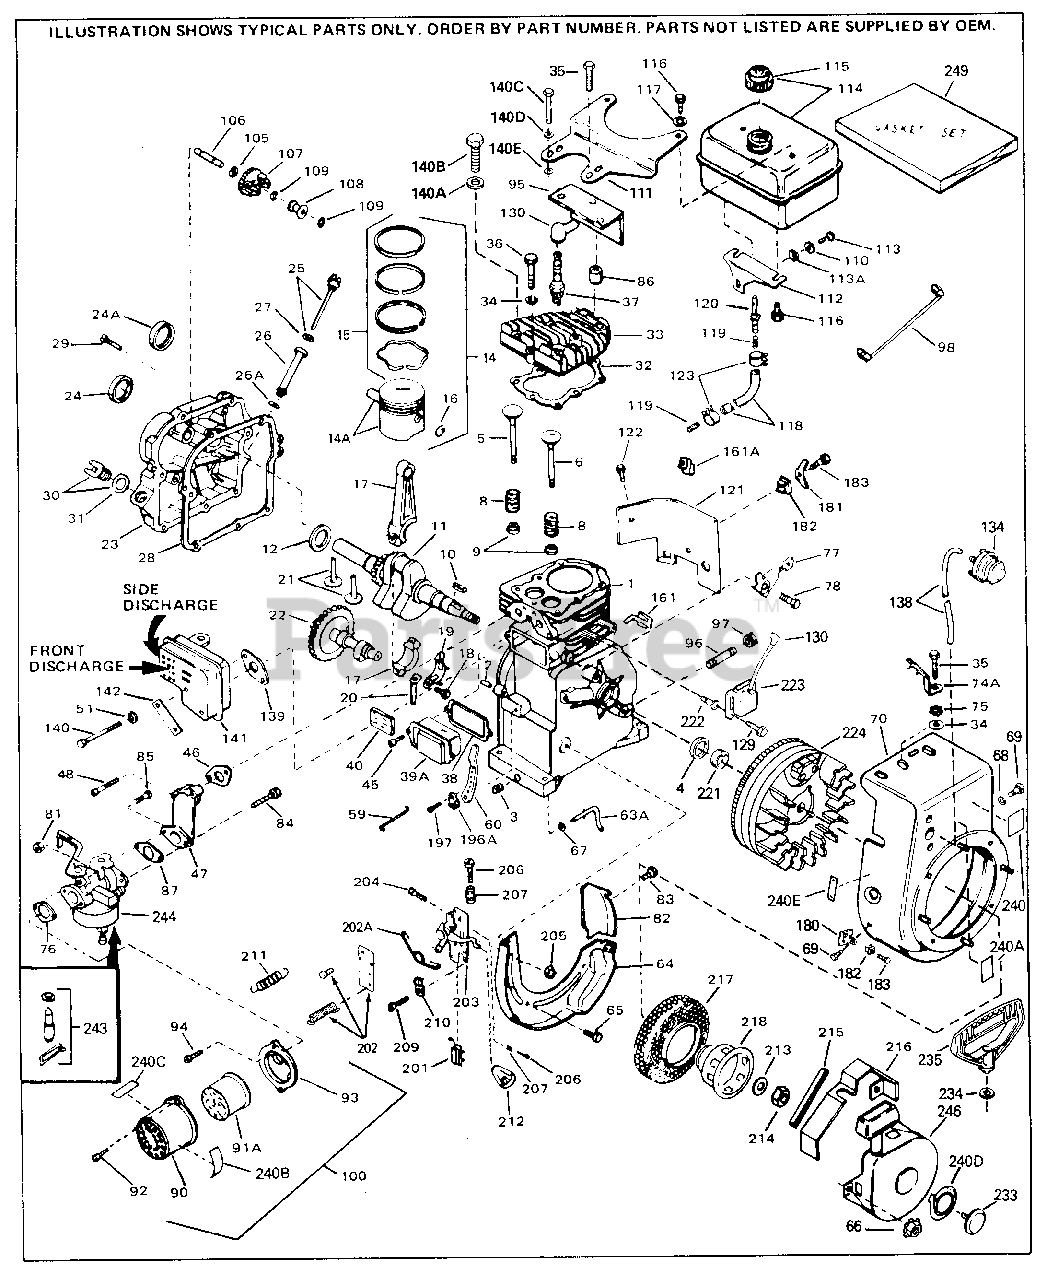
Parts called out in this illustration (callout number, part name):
1	"Cylinder (Incl. 2, 3 & 4) 2-13/16" Bo re
2	Dowel Pin
3	Oil Drain Plug (Sq. hd., 1/4-18)
4	Seal, Oil
5	Intake Valve (Std.) (Incl. 9)
5	Intake Valve (1/32" OS) (Incl. 9)
6	Exhaust Valve (Std.) (Incl. 151)
6	Exhaust Valve (1/32" OS) (Incl. 151)
8	Spring, Valve
9	Cap, Lower valve spring
10	Flywheel Key (also available in Packa ged Part #740007B)
11	Crankshaft
12	Washer, Thrust
14	Piston, Pin & Ring Set (Std.) 2-13/1 6" Bore
14	Piston, Pin & Ring Set (.010" OS)
14	Piston, Pin & Ring Set (.020" OS)
14A	Piston & Pin Ass'y. (Std.)(Incl. 16) 2-13/16"
14A	Piston & Pin Ass'y. (.010" OS) Incl. 16
14A	Piston & Pin Ass'y. (.020" OS) Incl. 16
15	Ring Set (Std.) (2-13/16" Bore)
15	Ring Set (.010" OS)
15	Ring Set (.020" OS)
16	Piston Pin Retaining Ring
17	Rod Assy., Connecting (Incl. 18 & 20)
18	Bolt, Connecting Rod
20	Dipper, Oil
21	Valve Lifter
22	Camshaft
23	Cover, Cylinder Incl. 24, 30, 31 & 1 06
24	Oil Seal
25	Dipstick (Incl. 27)
26	Tube Oil filler
27	"O" Ring
28	* Gasket, Cylinder cover
29	Screw, 1/4-20 x 1" (Use as required)
29	Screw, 1/4-20 x 1-1/4" Use as requir ed
32	Gasket, Cylinder head
33	Head, Cylinder( Incl. 35)
34	Washer (Use as required)
35	Screw, 5/16-18 x 2" (Use as required)
35	Screw, 5/16-18 x 1-1/2" Use as requir ed
36	Screw, 5/16-18 x 1-1/2" As req;not w /650691
37	Resistor Spark Plug (RJ-17LM)
38	* Gasket, Breather
39A	Breather Ass'y. (Incl. 38 & 40)
40	Element, Breather
45	Screw, 10-24 x 1/2"
46	* Gasket, Intake (1/32" thick)
47	Pipe, Intake
48	Screw, 1/4-20 x 1-19/32"
59	Link, Governor-to-throttle
60	Lever, Governor
63A	Rod, Governor (Incl. 67)
64	Baffle, Blower housing
65	Screw, 1/4-20 x 5/8"
66	Pop Rivet (Purchase locally) Use as r equired
66	Nut & Lock Washer 1/4-28 quired)
67	Flat Washer
68	Washer, Flat
69	Screw, 1/4-28 x 7/16"
70	Blower Housing (For electric starter) NOTE: In original production some s tarters are riveted to the blower hou sing. Replacement housing has thread ed studs. Order four nuts (29752) fo r remounting of starter.
77	Bracket, Holddown
78	Screw, 10-24 x 9/16"
81	Nut & Lock Washer 1/4-28
82	Extension, Baffle
83	Screw, 8-18 x 7/16"
84	Screw, 1/4-28 x 7/8"
85	Screw, 1/4-28 x 1-11/16"
87	* Gasket, Carburetor
94	Screw, 10-32 x 1/2"
95	Baffle, Heat
96	Nipple, Oil drain
97	Cap, Oil drain
98	Ground Wire
100	Air Cleaner Ass'y. (Incl. 76,76A,90A, 91A,92,93,94, & 221A)(Use as required )
105	Washer, Flat
106	Shaft, Mechanical governor
107	Gear Assy.,Governor (Incl. 105)
108	Spool Governor
109	Retaining Ring
111	Fuel Tank Bracket
113	Screw, 1/4-20 x 11/16"
113A	Washer, Flat
114	Fuel Tank (Incl. 115 & 123)
115	Fuel Cap (Red 1-1/2" ID) (also availa ble in Packaged Part #740005B) (Spur t resistant, Low profile)
115	Fuel Cap (Red Plastic) (1-3/16" I.D.) (Spurt resistant, High profile)
115	Fuel Cap (Std.)(Wh.Plastic) 1-1/2" I. D.
116	Screw, 1/4-15 x 7/8"
118	Line, Fuel (Braided 32")
118	Fuel Line (8.62")
118	Line, Fuel (Braided 16")
121	Blower Housing Extension
122	Screw, 10-24 x 1/2"
123	Fuel Line Clamp
129	Screw, 1/4-20 x 5/8"
130	Cover, Spark plug
134	Primer Assy.
138	Line, Primer
139	* Gasket, Muffler
140	Screw, T-30, 1/4-20 x 1/2"
140	Screw, 1/4-20 x 2-1/2"
140A	Flatwasher, 1/4"
140B	Screw, T-30, 1/4-20 x 1/2"
140C	5/16-18 x 2-3/8"
141	Muffler (Side Discharge)
180	Bracket, Grommet mounting
182	Breather Tube Grommet
183	Screw, 8-32 x 3/8"
196A	Clamp, Governor lever
197	Screw, 8-32 x 5/16"
201	Terminal Assy. (Use as required)
203	Control Brkt In.201,204,205,206,207,2 09,210
204	Screw, 10-24 x 9/16"
204	Screw, 8-32 x 1/2" (Use as required)
204	Screw, 8-32 x 3/8" (Use as required)
205	Lock Nut, 8-32
206	Screw, 5-40 x 7/16" Used on late pro duction
206	Screw, 10-32 x 1" Used on early produ ction
207	Compression Spring Used on late produ ction
207	Compression Spring Used on early pro duction
209	Screw, 10-32 x 3/8"
210	Conduit Clip
211	Spring, Extension
213	Washer, Belleville
214	Nut, Flywheel
216	Guard, Starter
217	Screen, Starter
218	Cup, Starter
221	Spacer, Flywheel key
222	Stud, Solid State Assy.
243	Inlet Needle, Seat & Clip Assy.
244	Carburetor (Incl. 87) (Refer to Divis ion 5, Section A, page 168 for breakd own)
246	Rewind Starter Refer to Division 5, S ection C, page 29 for breakdown
249	* Gasket Set (Incl. items marked *)
